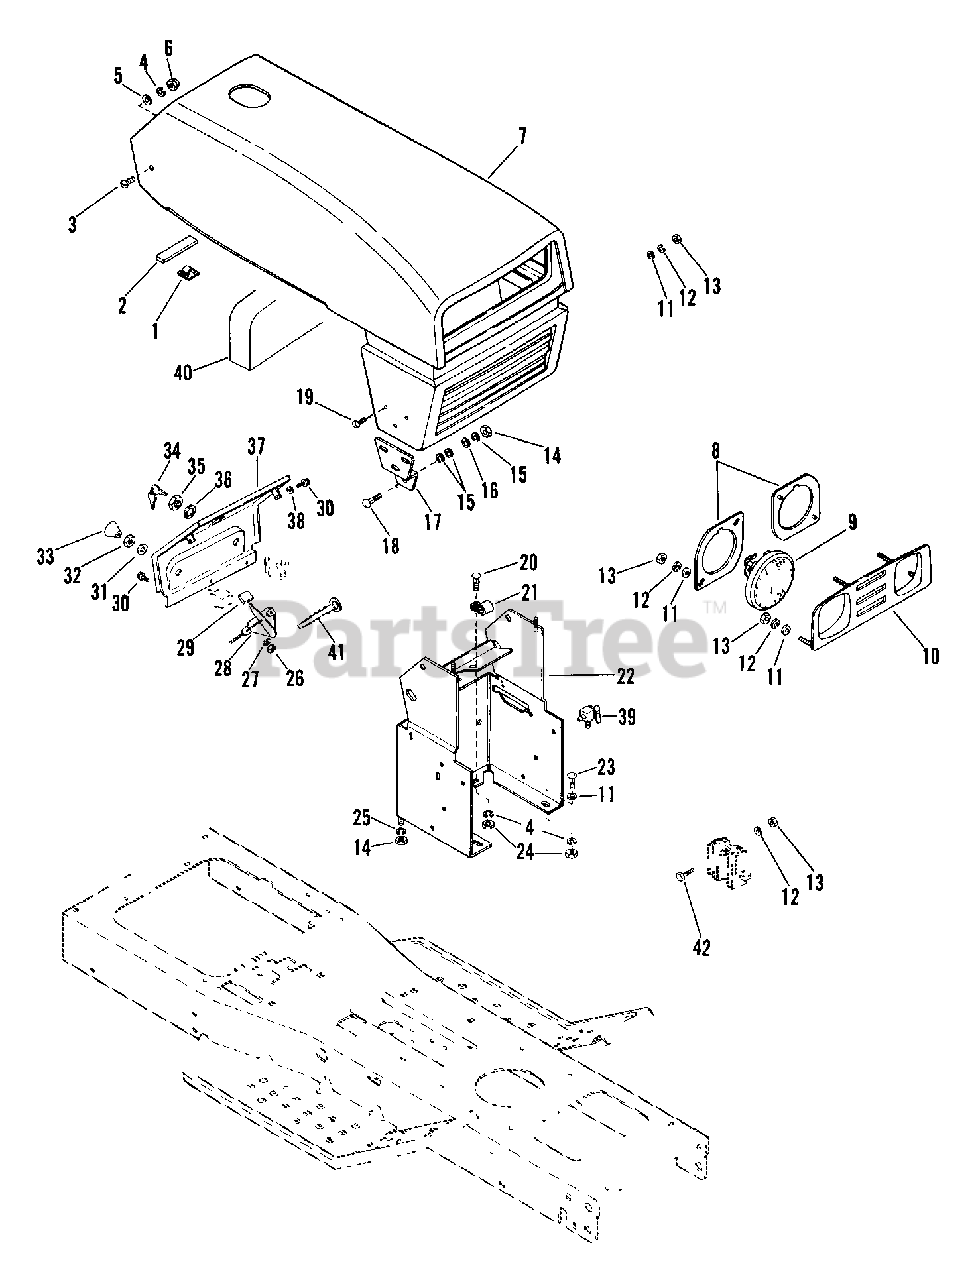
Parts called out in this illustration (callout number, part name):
1	WIRE CLIP
2	FOAM TAPE
3	SCR-MCH .31-18X.50 SLTR PL
4	WSHR-LK .312X.097 PL HVY
5	WSHR-FL-STL .38X.875X.083 PL
6	NUT-CROWN .312-18 PL
7	HOOD & GRILL
8	HEAD LIGHT RETAINER RING
9	HEAD LIGHT
10	HEADLIGHT INSERT
11	WSHR-FL-STL.312X.734X.065PL
12	WSHR-LK .250X.077 HVY PL
13	NUT-HEX .250-20 PL
14	NUT-HEX .375-16
15	WSHR-LK .375X.094 MED PL
16	WSHR-FL-STL .438X1.0X.083 PL
17	HOOD HINGE
18	BLT-RDHDSQSHNK .38-16X1.00 PL
19	SCR .25-20X.75 TS PH PL
20	BLT-HEX .31-18X.75 PL GR5
21	J-CLAMP
22	DASH BASE WITH DECALS
23	BLT-RDHDSQNK .31-18X.75 GR5 PL
24	NUT-HEX .312-18
25	WSHR-LK .375X.115 HVY PL
26	NUT-HEX 10-24 PL
27	WSHR-LK 10X.047 MED PL
28	THROTTLE CONTROL
30	SCR-SHT.MET10-16X.375 HWH PL B
31	WSHR-FL-STL .382X.812X.023 PL
32	NUT .50-20 PL
34	KEYS
35	NUT .562-24
36	WSHR-LK-INT .563X.040 PL
37	DASH
37	DASH YT12
38	WSHR-FL-STL .250X.562X.049 PL
39	BALL VALVE
40	BAFFLE-HOOD
41	TIE DOWN
42	BLT-HEX .25-20X1.00 GR2
